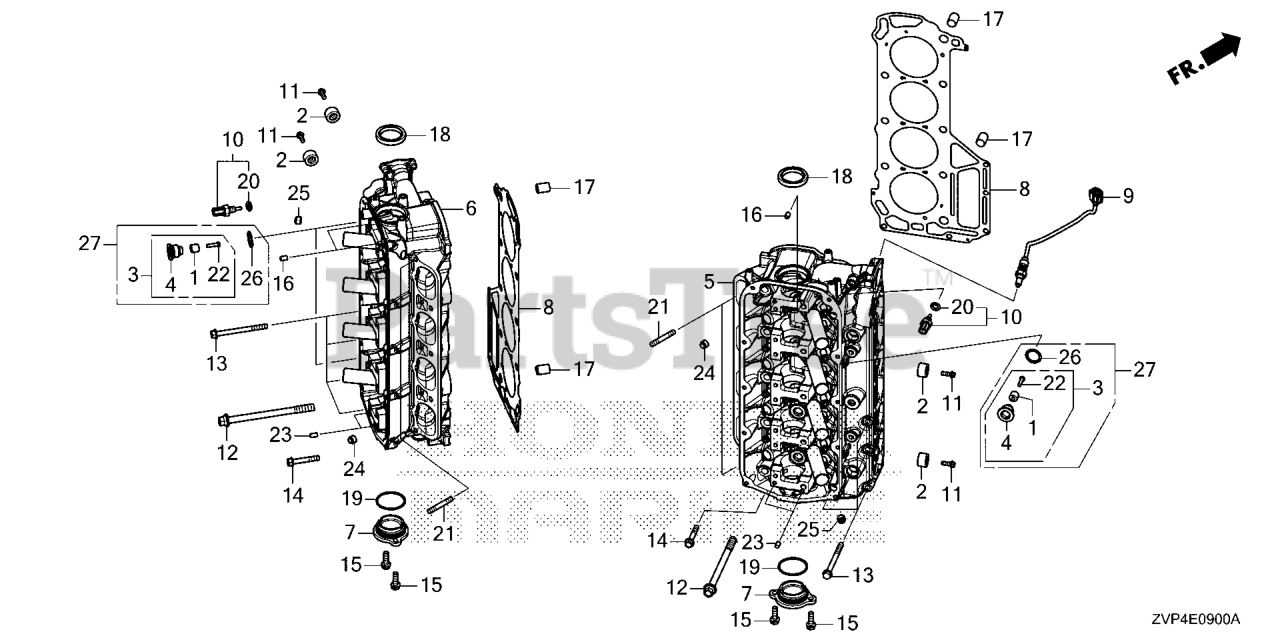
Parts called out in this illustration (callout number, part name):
1	METAL, ANODE
2	METAL, ANODE
3	BOLT, SEALING (22MM)
4	BOLT, SEALING (22MM)
5	HEAD COMP, CYLN R
6	HEAD COMP, CYLN L
7	COVER, L. CAMSHAFT THRUST
8	GASKET COMP
9	SENSOR, OXYGEN
10	SENSOR ASSY., WATER TEMPERATURE
11	BOLT, FLANGE (6X18)
12	BOLT-WASHER (12X163)
13	BOLT, FLANGE (8X95)
14	BOLT, FLANGE (8X50)
15	BOLT, FLANGE (8X25)
16	PIN, DOWEL (6X10)
17	PIN, DOWEL (16X22)
18	OIL SEAL (39X53X8) (NOK)
19	O-RING (48.5X2.4)
20	O-RING (9.5X1.9)
21	BOLT, STUD (8X40)
22	SCREW, PAN (5X20)
23	PIN B, DOWEL (6X10)
24	SEAL A, VALVE STEM (NOK)
25	SEAL B, VALVE STEM (NOK)
26	WASHER, SEALING (22MM)
27	BOLT KIT (22MM)
